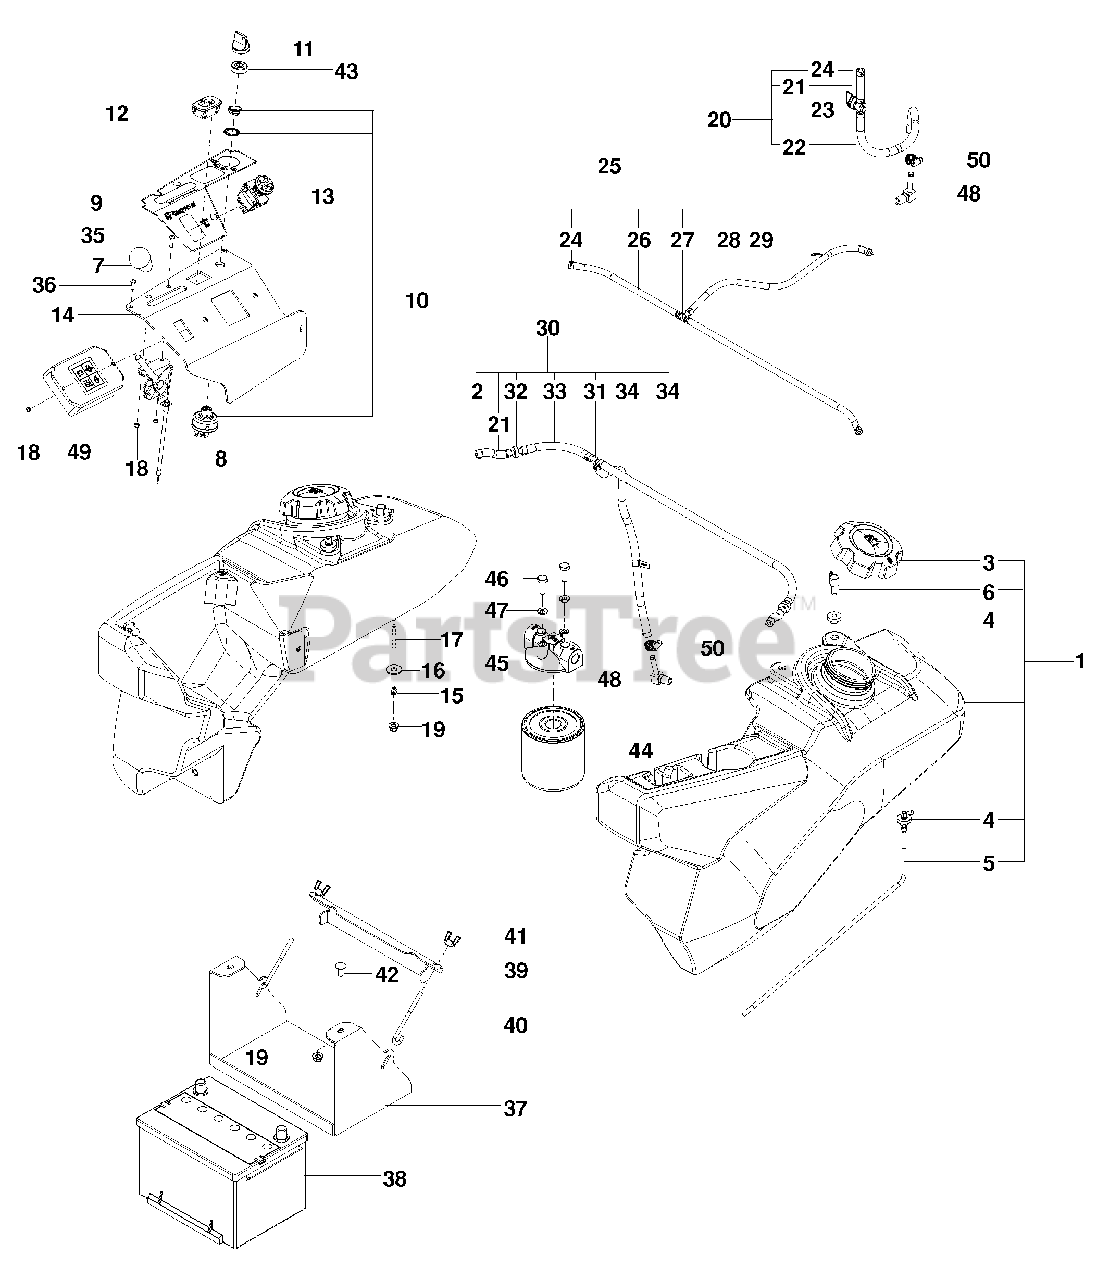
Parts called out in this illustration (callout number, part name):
1	Tank Assy, Lt
3	Cap, Diesel Fuel
4	Grommet, Rubber
5	Fitting, Fuel
6	Fitting, Return
8	Cable, Throttle
9	Decal, Control
10	Switch, Ignition
11	Key, Ignition
12	Hour Meter
13	Switch, Pto 10 Amp
14	Panel, Control Gry
15	Spring, Tank Mount
16	Washer 5/16 Sae Flat
17	Stud, Fuel Tank
18	Nut 10-24 Hex Nyloc
19	Nut 5/16-18 Hex Flange Nyloc
20	Line, Fuel Assy
21	Fuel Line 2 1/2"
22	Fuel Line 14"
23	Valve, Fuel
24	Clamp, Hose
25	Line, Fuel Assy Return
26	Hose, Fuel 9 1/2
27	Tee, Fuel Line
28	Fuel Line 17 1/4"
29	Fuel Line 18 1/2"
30	Line, Fuel Assy
31	Tee, Fuel Line
32	Valve, Check
33	Fuel Line 5"
34	Fuel Line 21"
35	SCREW 3/8-16 x 1 1/2 HEX HD
36	Screw 10-24 X 3/8 Skt Hd
37	Box, Battery Blk
38	Battery, 500 Cca
39	Bracket, Battery Mount
41	Wingnut 1/4-20 Nyloc
42	Rhsnb 5/16-18 X 3/4
43	Nutcap, Ignition
44	Filter, Fuel
45	Head, Fuel Filter
46	Hcs 1/4-20 X 3/4
47	Washer 1/4 Splt Lk
48	Fitting, 90O
49	Module, Control
